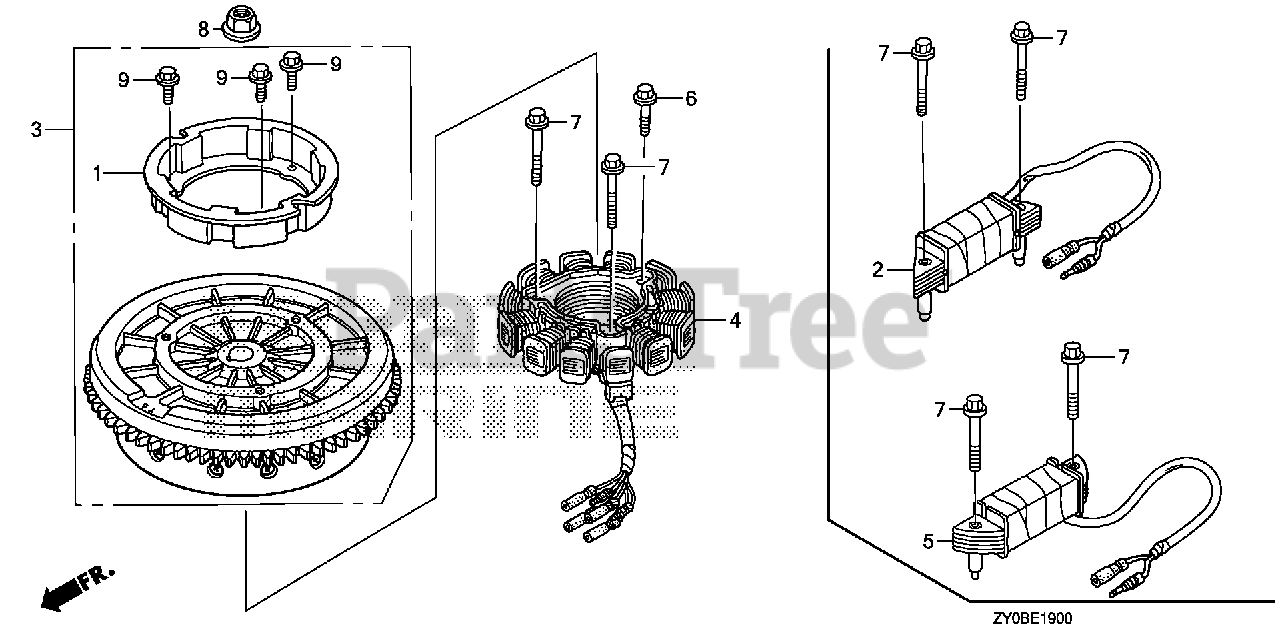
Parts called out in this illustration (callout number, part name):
1	PULLEY, STARTER
2	COIL ASSY., POWER
3	FLYWHEEL *TBLACK* (BLACK)
5	COIL ASSY., CHARGE (6A)
7	BOLT, FLANGE (6X52) (CT200)
8	NUT, SPECIAL (16MM)
9	BOLT, FLANGE (6X10)
